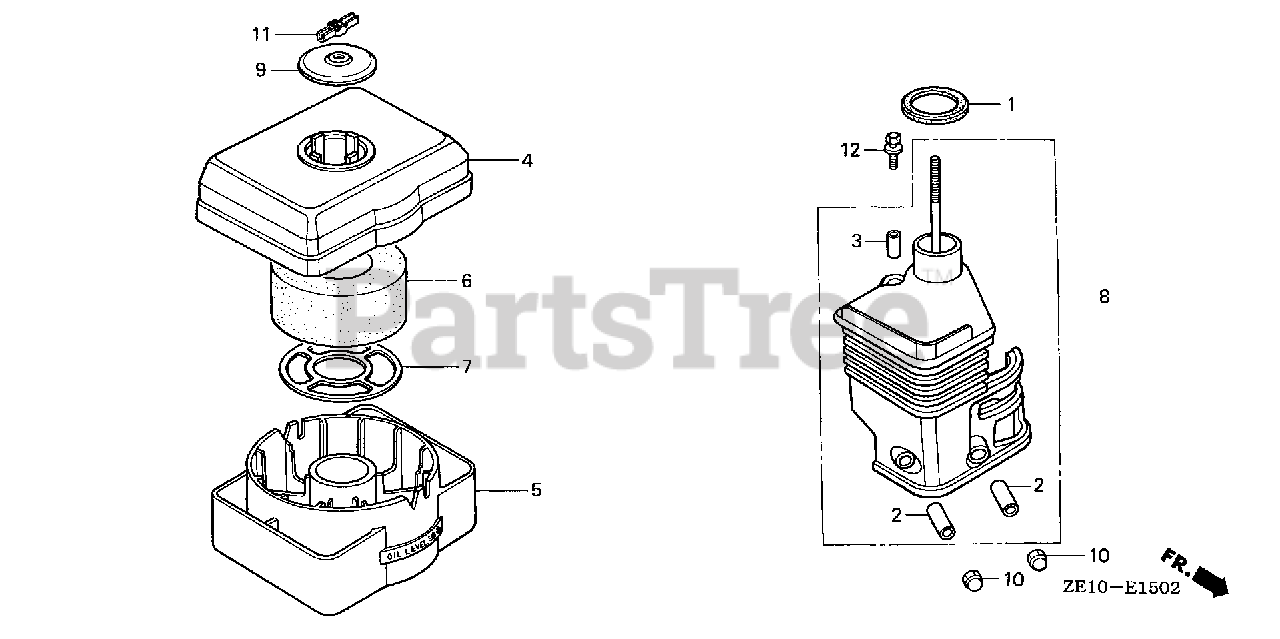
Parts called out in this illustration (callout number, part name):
1	GASKET, ELBOW
2	COLLAR, AIR CLEANER Use up to Engine SN 1786084.
2	COLLAR, AIR CLEANER Use from Engine SN 1786085.
3	COLLAR B, AIR CLEANER
4	BODY, CLEANER (OIL BATH)
5	PAN, CLEANER OIL (OIL BATH)
6	ELEMENT, AIR CLEANER
7	GRID, AIR CLEANER
8	ELBOW, AIR CLEANER Use from Engine SN 1220570 to 1786084.
8	ELBOW, AIR CLEANER Use from Engine SN 1786085.
8	ELBOW, AIR CLEANER Use up to Engine SN 1220569.
9	CAP, CLEANER
10	NUT, CAP (6MM)
11	NUT, AIR CLEANER COVER
12	BOLT-WASHER (6X20)
